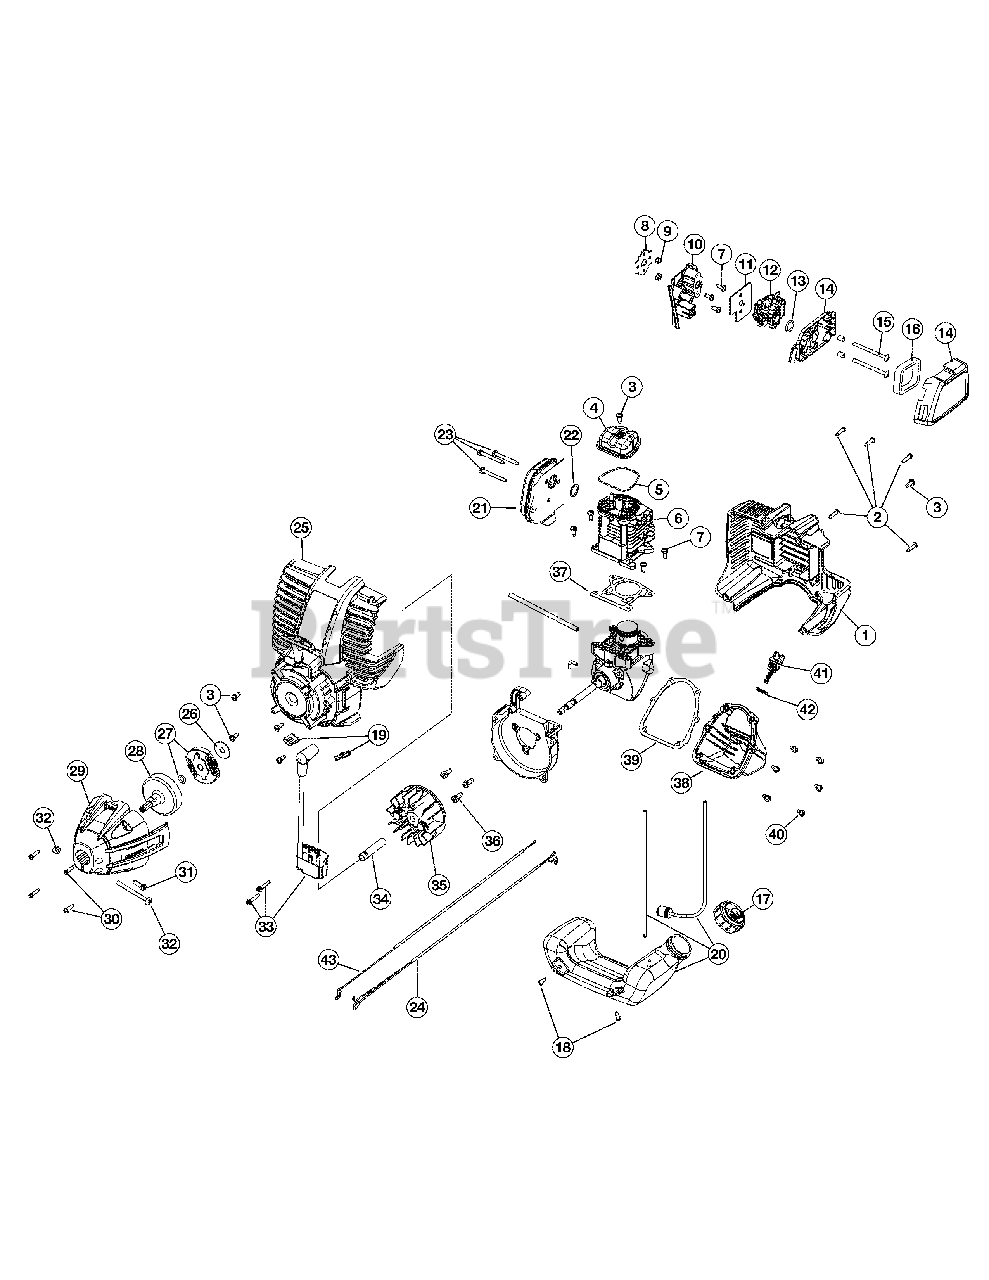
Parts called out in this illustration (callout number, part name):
1	Engine Cover
4	Valve Cover
5	Valve Cover Gasket
6	Cylinder Assembly (Incl. Ref No. 5, 7 & 43)
7	Cylinder Screw
8	Insulator Gasket
10	Insulator (Incl. Ref No. 11)
11	Carburetor Gasket
12	Carburetor w/Primer
13	Carburetor O-Ring
14	Air Filter Cover Assembly (Incl. Ref No. 16)
15	Air Filter Mounting Screw
16	Air Filter
17	Fuel Cap
19	Clip Nut
20	Fuel Tank Assembly (Incl. Ref No. 17)
21	Muffler Assembly (Incl. Ref No. 22 & 23)
22	Muffler Gasket
23	Muffler Mounting Screw
24	Lead Wire
25	Starter Housing Assembly (Incl. Ref No. 3)
26	Washer
27	Clutch Assembly
28	Clutch Drum
29	Clutch Cover Assembly (Incl. Ref No. 30-32)
30	Cover Screw
31	Anti-Rotation Screw
32	Clamping Screw Assembly
33	Ignition Module Assembly
34	Spacer
35	Flywheel
36	Shroud Screw
37	Cylinder Gasket
38	Oil Pan (Incl. Ref No. 39 & 40)
39	Oil Pan Gasket
40	Oil Pan Screw
41	Dipstick Assembly (Incl. Ref No. 42)
43	Throttle Cable
